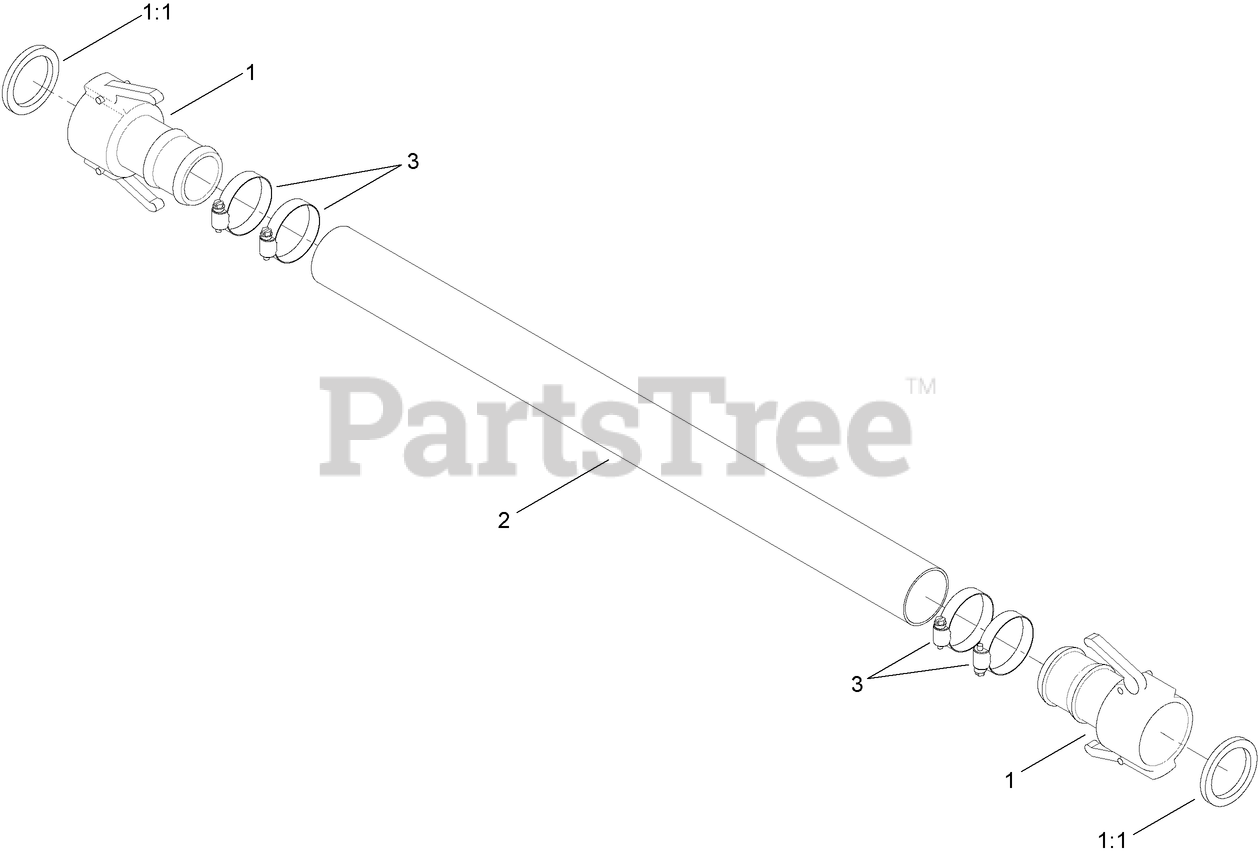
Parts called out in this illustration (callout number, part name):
1	COUPLER-LOCK, CAM
1:1	GASKET
2	HOSE-DISCHARGE
3	CLAMP-HOSE
